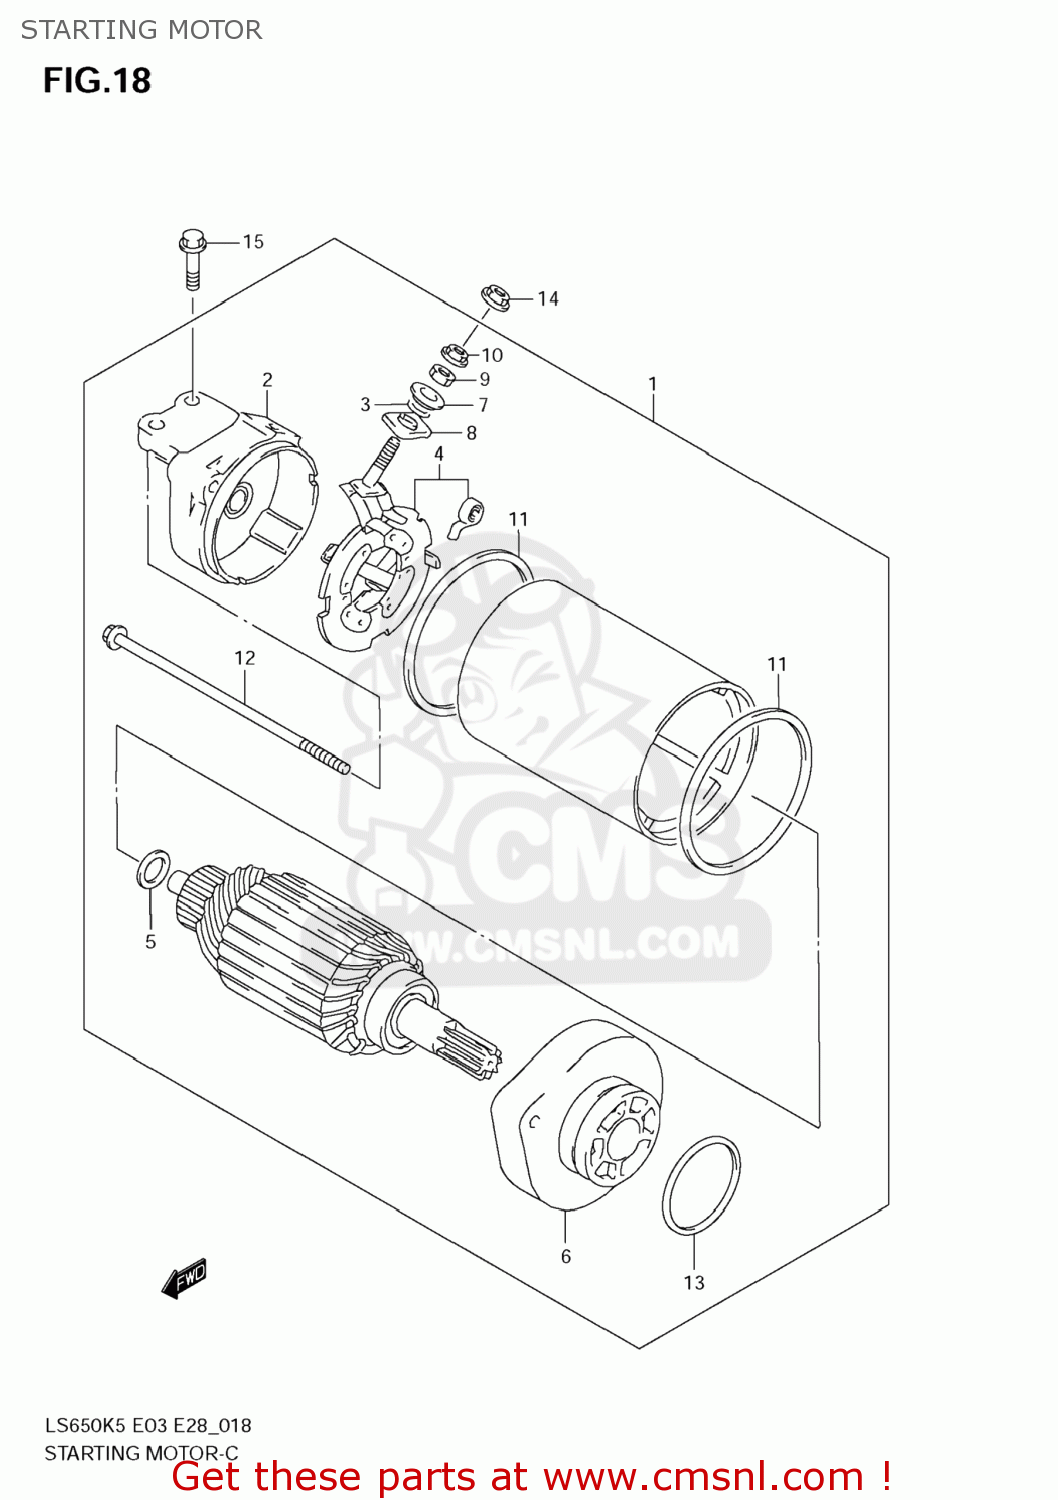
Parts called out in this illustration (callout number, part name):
1	MOTOR ASSY,STARTING
2	FRAME ASSY
3	O RING
4	HOLDER SET,BRUSH
5	SHIM SET,STARTING MOTOR
6	BRACKET SET
7	BUSHING
8	BUSHING
9	NUT
10	NUT
11	O RING
12	BOLT
13	O-RING (D:2.1 ID:34.7)
14	NUT
15	BOLT(6X20)
